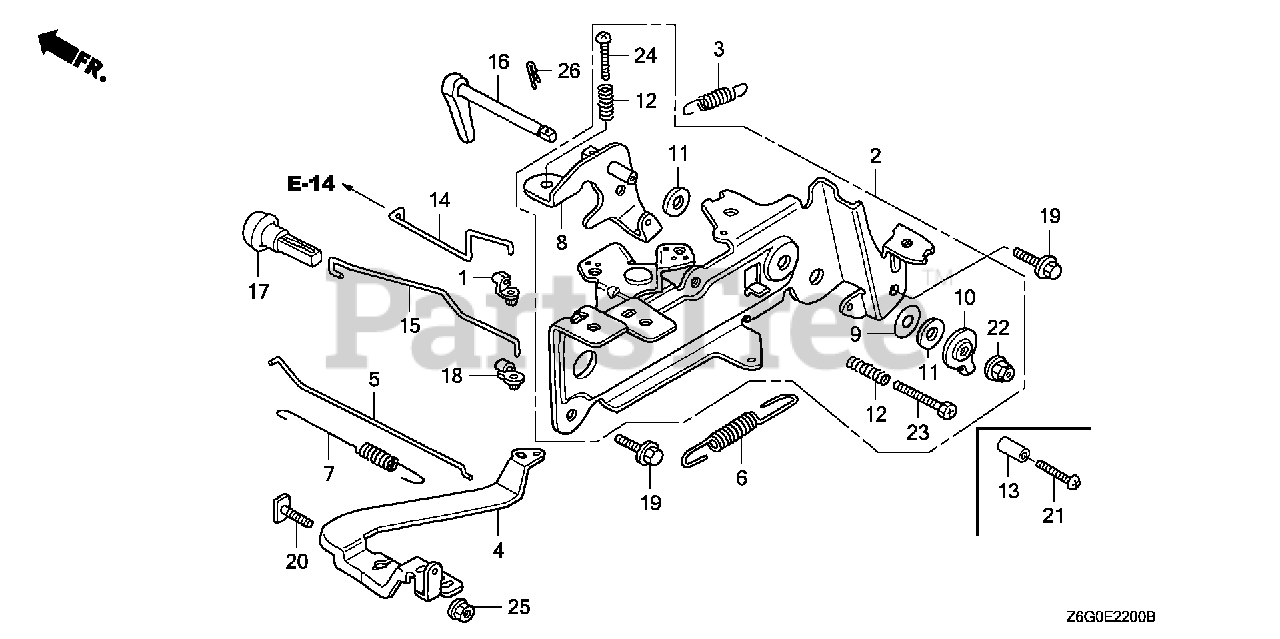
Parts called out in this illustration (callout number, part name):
1	JOINT, ROD
2	CONTROL ASSY.
3	SPRING, STARTER
4	ARM, GOVERNOR
5	ROD, GOVERNOR
6	SPRING, GOVERNOR (MANUAL)
7	SPRING, THROTTLE RETURN
8	ARM, CONTROL
9	SPRING, LEVER Use from Engine SN 2327377.
10	WASHER, CONTROL ARM
11	SPACER, CONTROL LEVER Use from Engine SN 2327377.
12	SPRING, CONTROL ADJUSTING Use from Engine SN 2327377.
14	ROD, CHOKE CONTROL
15	ROD, CHOKE KNOB
16	LEVER ASSY., THROTTLE
17	KNOB, CHOKE
18	BUSH, LINKAGE
19	BOLT, FLANGE (6X14)
20	BOLT, GOVERNOR ARM
22	NUT, SELF-LOCK (6MM)
23	BOLT, SLOT (5X25)
24	SCREW, PAN (5X25)
25	NUT, FLANGE (6MM)
26	PIN, LOCK (10MM)
